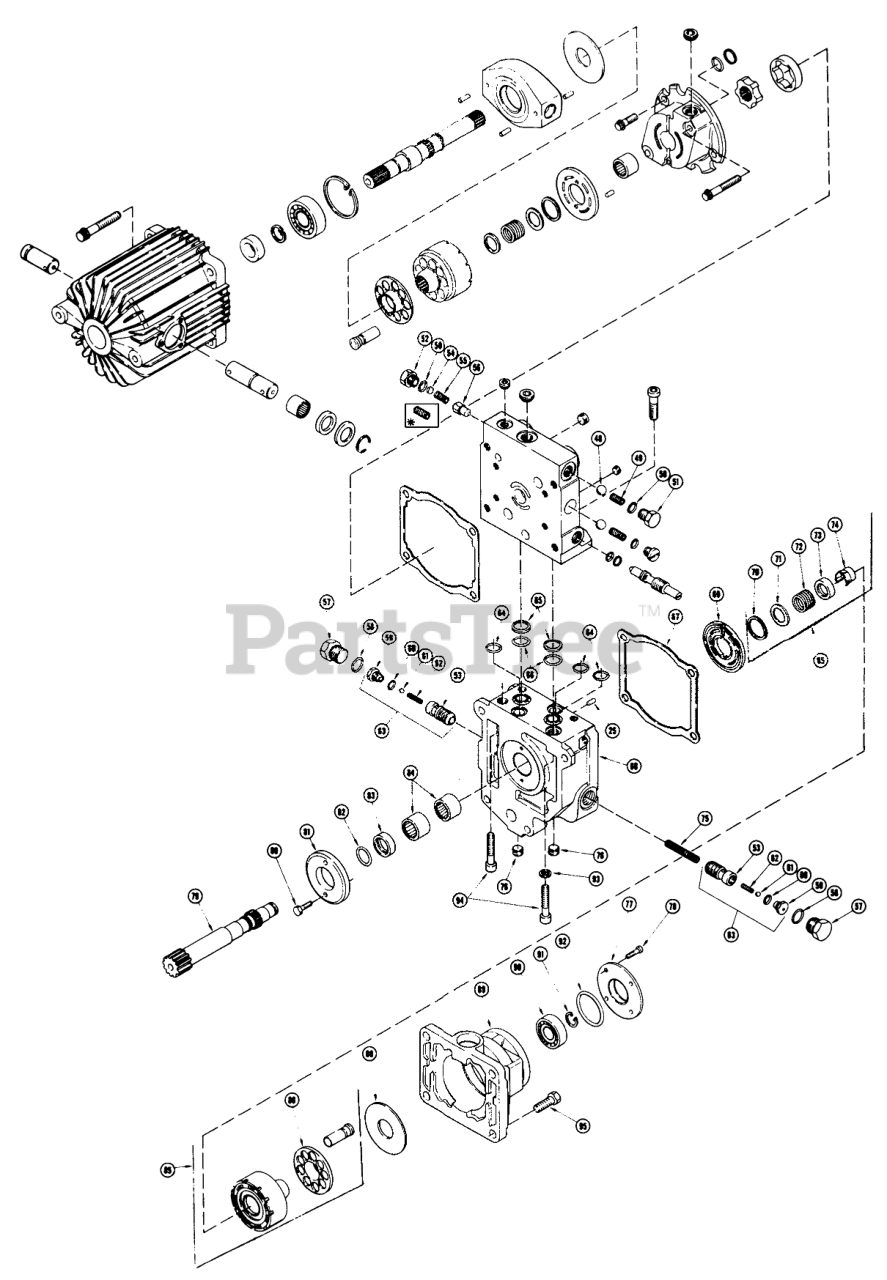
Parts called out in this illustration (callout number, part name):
48	Ball
49	Spring Chg. Rel. Valve
50	O RING
51	Plug
53	Sleeve
54	Shim Set
55	Spring-Implement Valve
55	Spring Chg. Rel. Valve
56	Cone
58	O-RING
59	Valve
60	O-Ring
62	SPRING
63	Sleeve
64	O RING
65	RING BACKUP
66	O RING
67	Gasket-Motor
68	End Cap-Motor
69	Valve Plate
70	RING-SUN9006250-0112
71	WASHER-9009625-0018
72	Spring
73	SEAT-SUND 3102407
74	Retaining Clip
75	Spring
76	Pipe Plug
77	Plate
78	Cap Screw
79	Motor Shaft
80	Cap Screw
82	O-RING--9004175-0001
83	Bellcrank Assembly
84	Needle Bearing
85	Cyl Blk Kit Inc 17-23
86	RETAINER-SUN 3100194
88	Thrust Plate
89	Motor Housing
90	BALL BRG9001305-0004
91	RING-SUN9006300-0059
92	O-RING
93	Copper Washer
94	Socket HD Cap Screw
95	Hex Head Cap Screw
